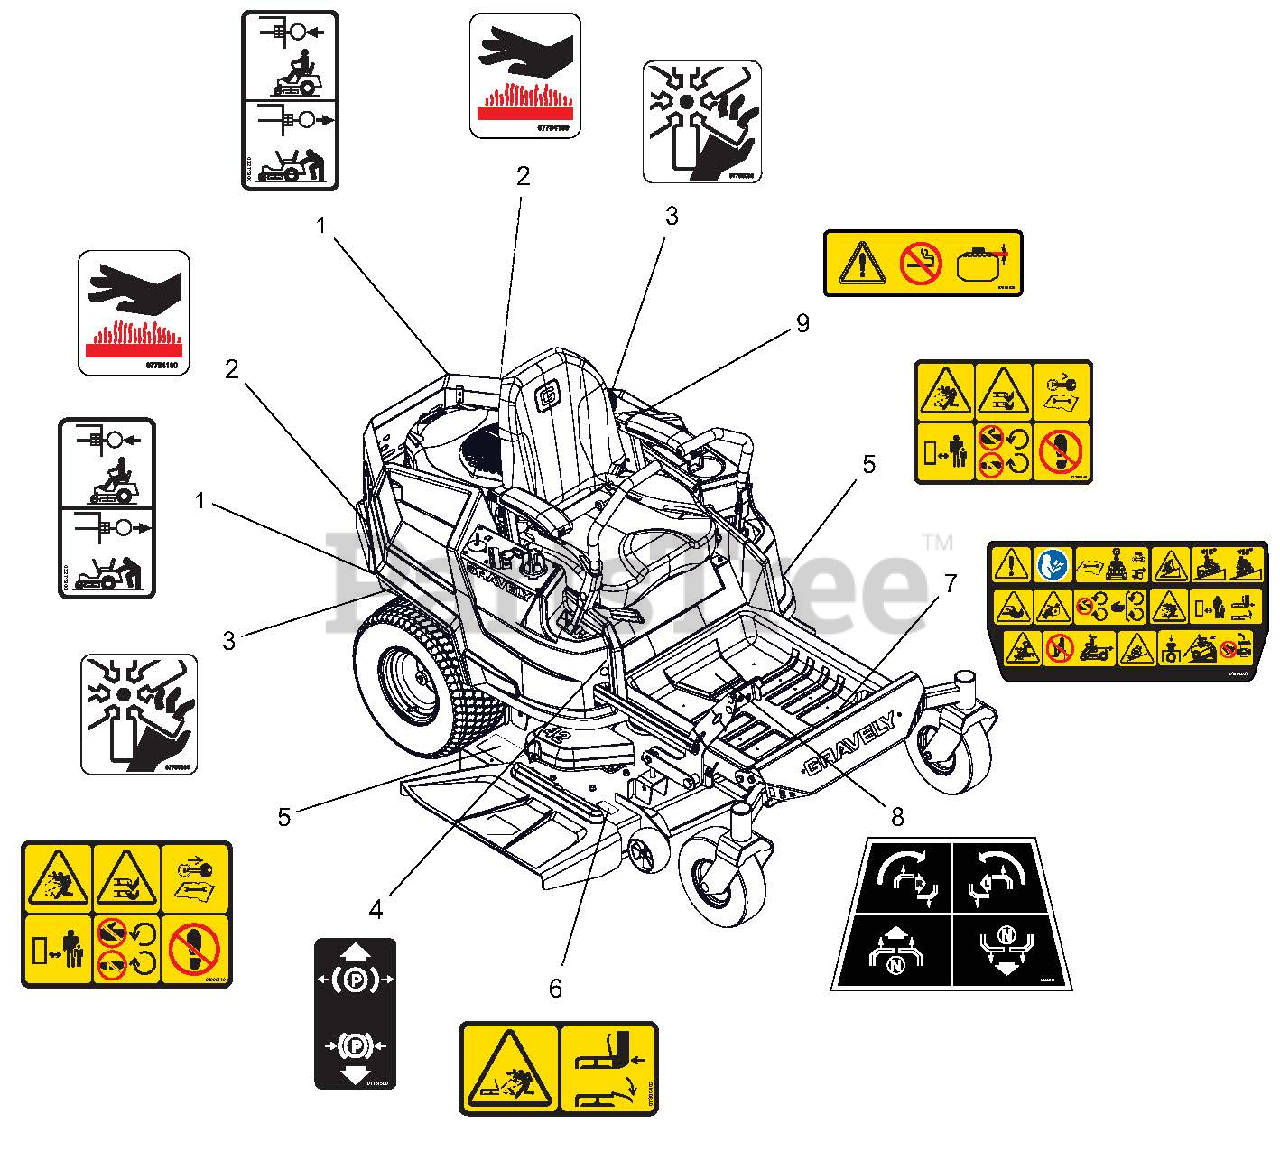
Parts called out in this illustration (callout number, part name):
1	DECAL, TRANSMISSION DISCONNECT
2	DECAL, HOT SURFACE
3	DECAL, DANGER FAN
4	DECAL, PARKING BRAKE LEVER
5	DECAL, SAFETY - MOWER DECK
6	DECAL, SAFETY - DECK GUARDING
7	DECAL, MAIN SAFETY
8	DECAL, STEERING
9	DECAL-FUEL, WARNING
